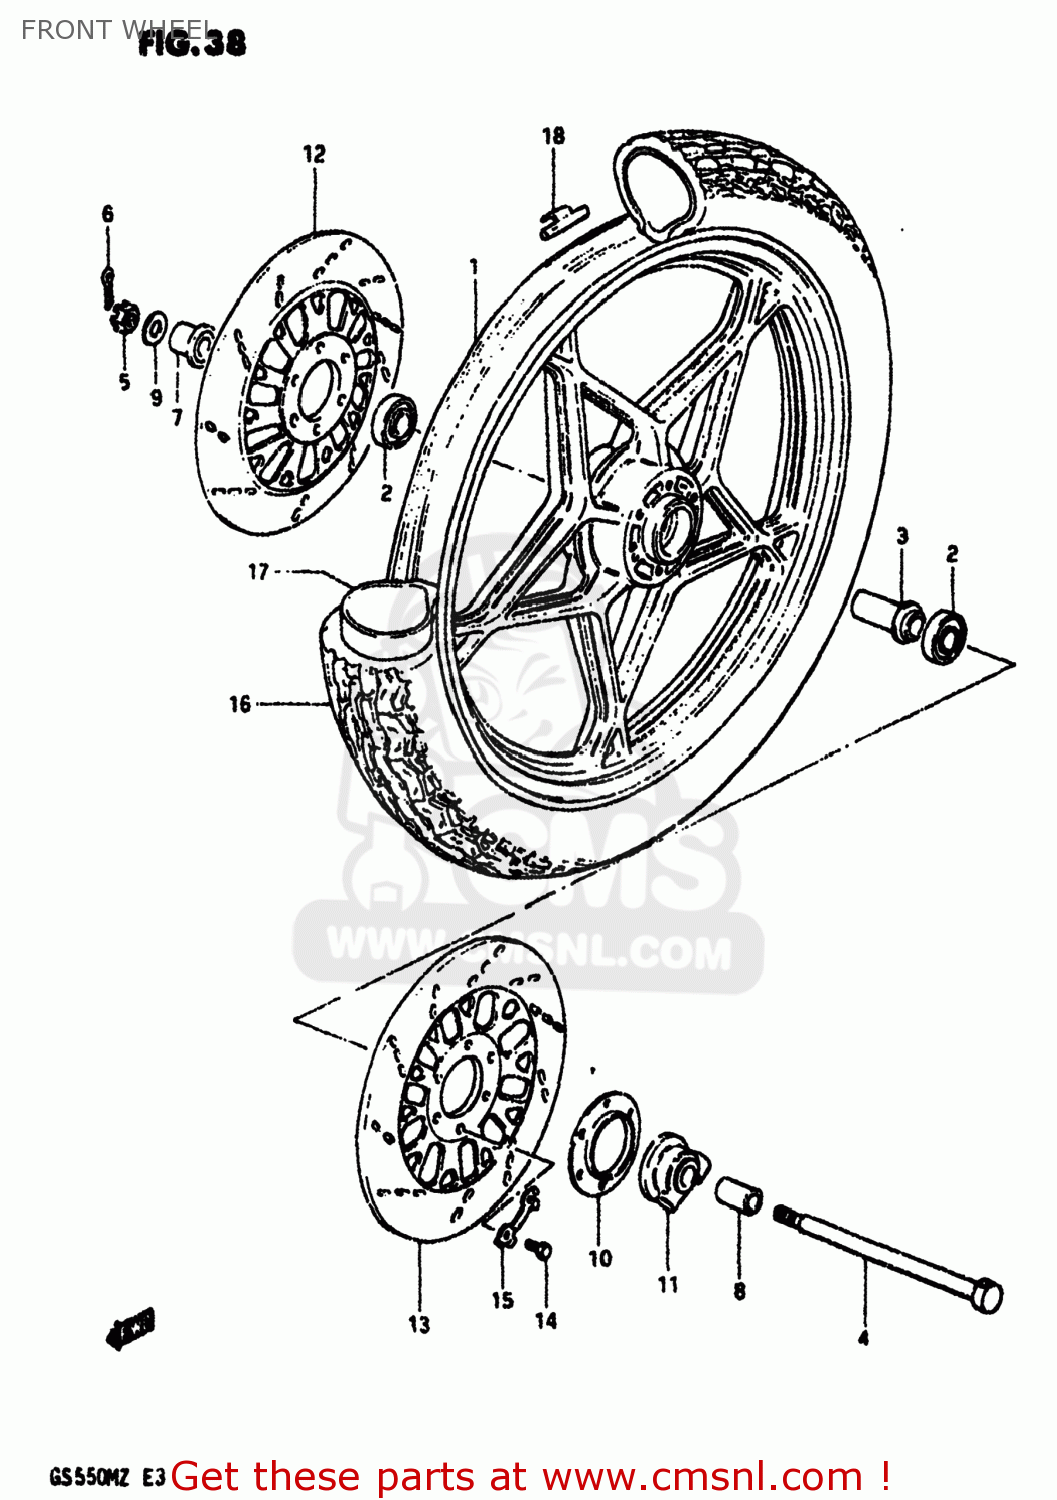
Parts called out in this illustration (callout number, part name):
1	WHEEL, FRONT (19X1.85) (GRAY)
2	BEARING
3	SPACER,FR HUB BEARING
4	AXLE,FRONT
5	NUT 12MM
6	COTTER PIN
7	SPACER,FR HUB BEARING,R
8	SPACER(15X22X30)
9	WASHER
10	DUST SEAL,SPEEDOMETER GEAR BOX
11	BOX ASSEMBLY,SPEEDOMETER GEAR
12	DISC,BRAKE
13	DISC,BRAKE
14	BOLT(8X28)
15	WASHER
16	TIRE,FRONT
17	TUBE,INNER
18	BALANCER,WHEEL
